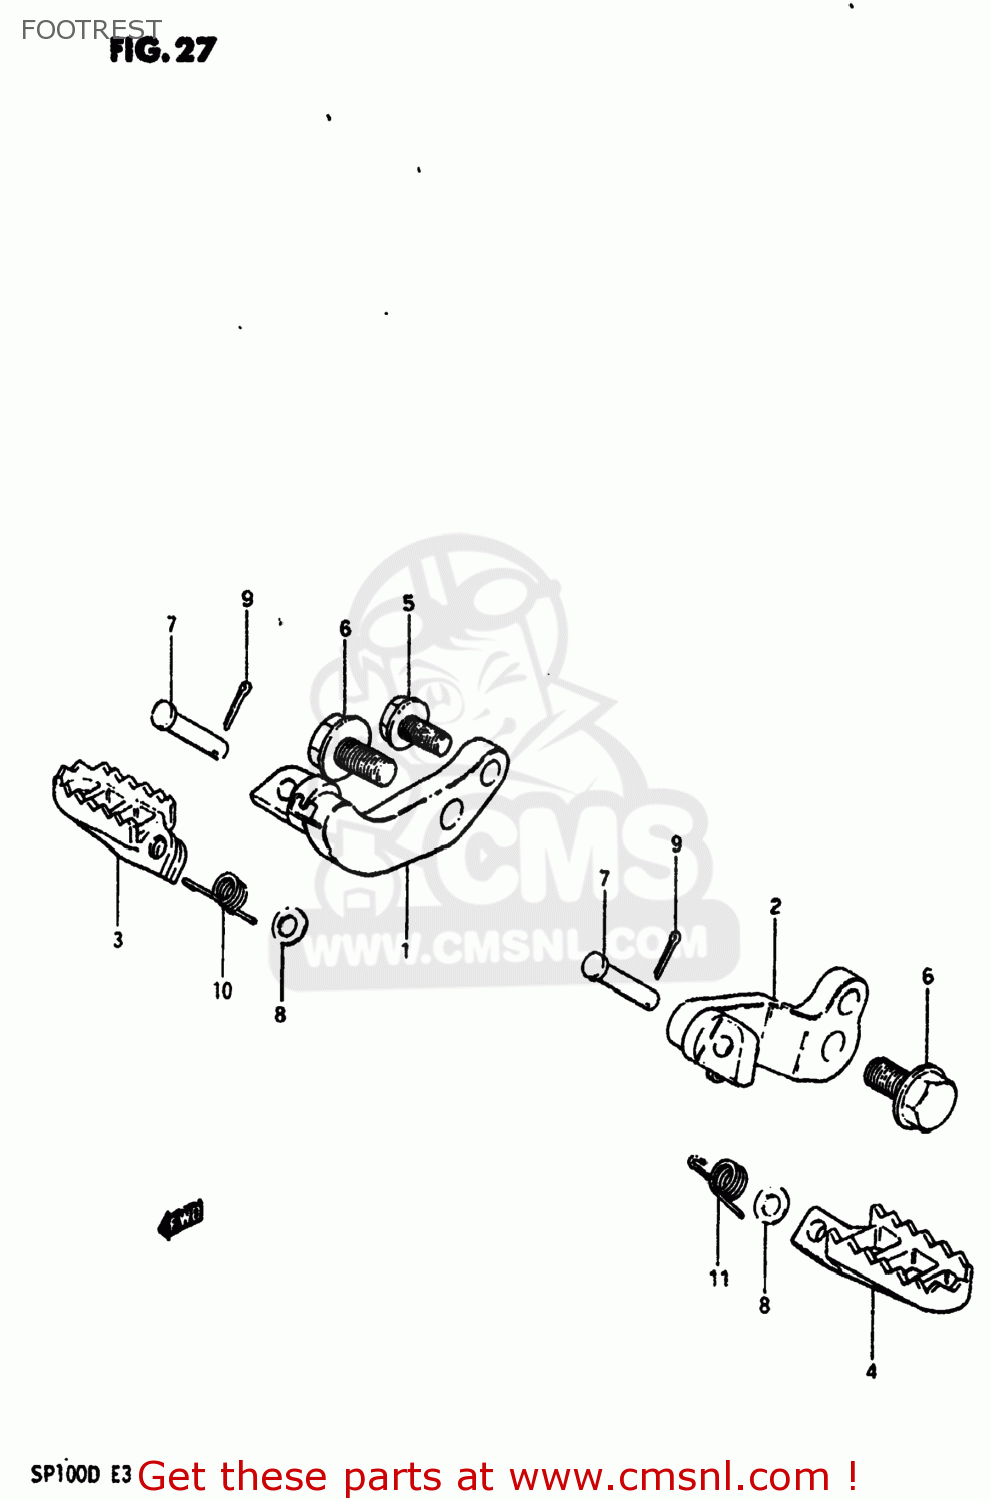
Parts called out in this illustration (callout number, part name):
1	BAR,FRONT FOOTREST
2	BAR,FRONT FOOTREST,LEFT
3	FOOTREST,RIGHT
4	FOOTREST
5	BOLT
6	BOLT
7	PIN
8	WASHER(8.5X13X1.6)
9	PIN 20X20
10	SPRING
11	SPRING,FOOTREST,LEFT
